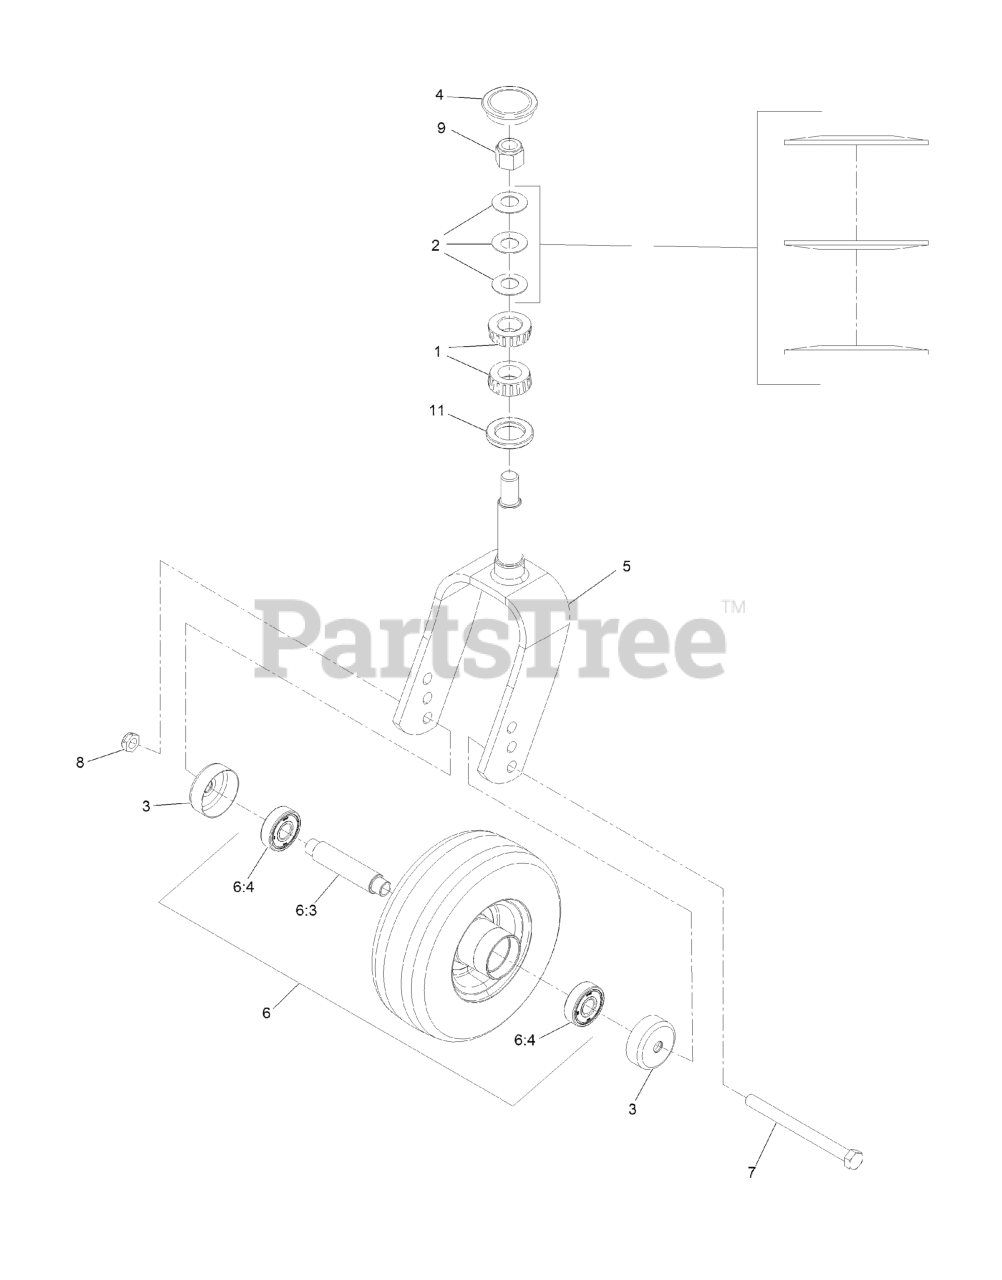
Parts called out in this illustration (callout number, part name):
1	Cone-Bearing Tapered Roller
2	WASHER-BELLVILLE
3	GUARD, SEAL
4	CAP-GREASE
5	FORK-CASTER 9"
6	WHEEL AND TIRE ASM
6:3	AXLE-CASTER
6:4	BEARING
7	SCREW-HH
8	NUT-HEX
9	NUT-LOCK, NI
11	SEAL-GREASE
